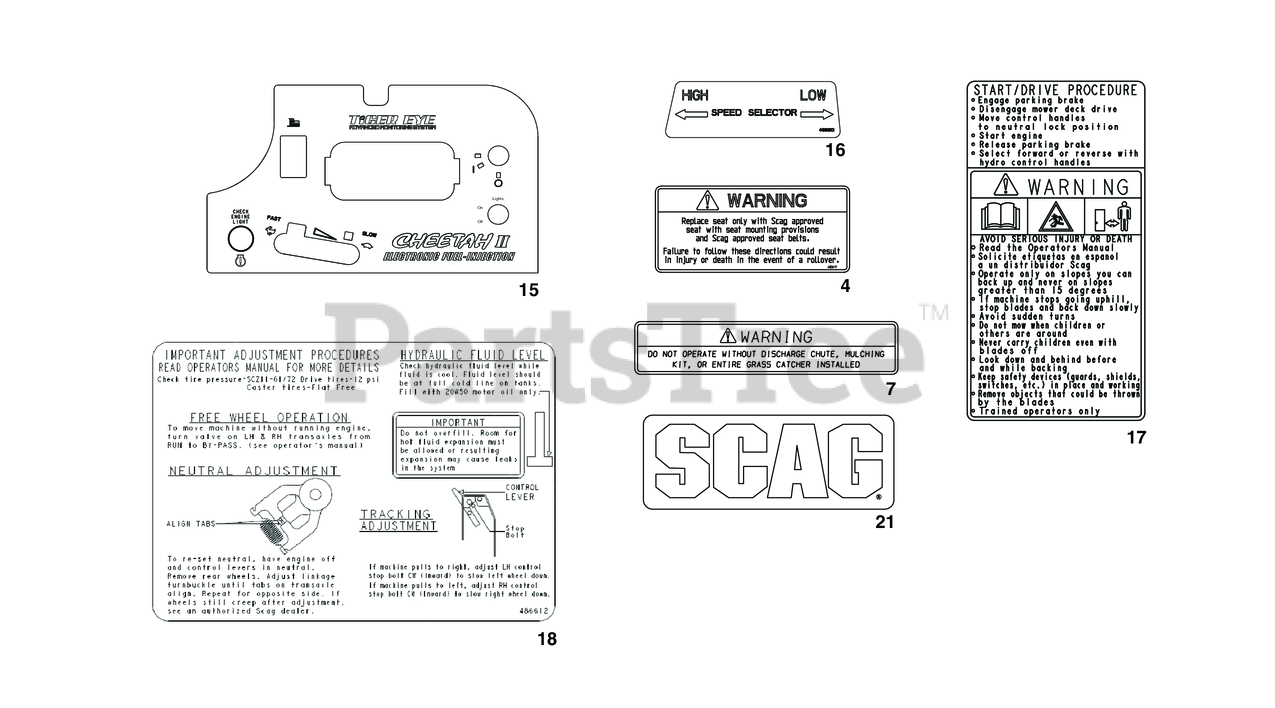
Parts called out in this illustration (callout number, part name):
4	Decal, Seat Replacement
7	Decal, Warning-Discharge
15	Decal, Instrument Panel - SCZII - EFI
16	Decal, Speed Control
17	Decal, Start / Drive
18	Decal, Adjustments - SCZII
21	Decal, Scag - Fuel Tank
